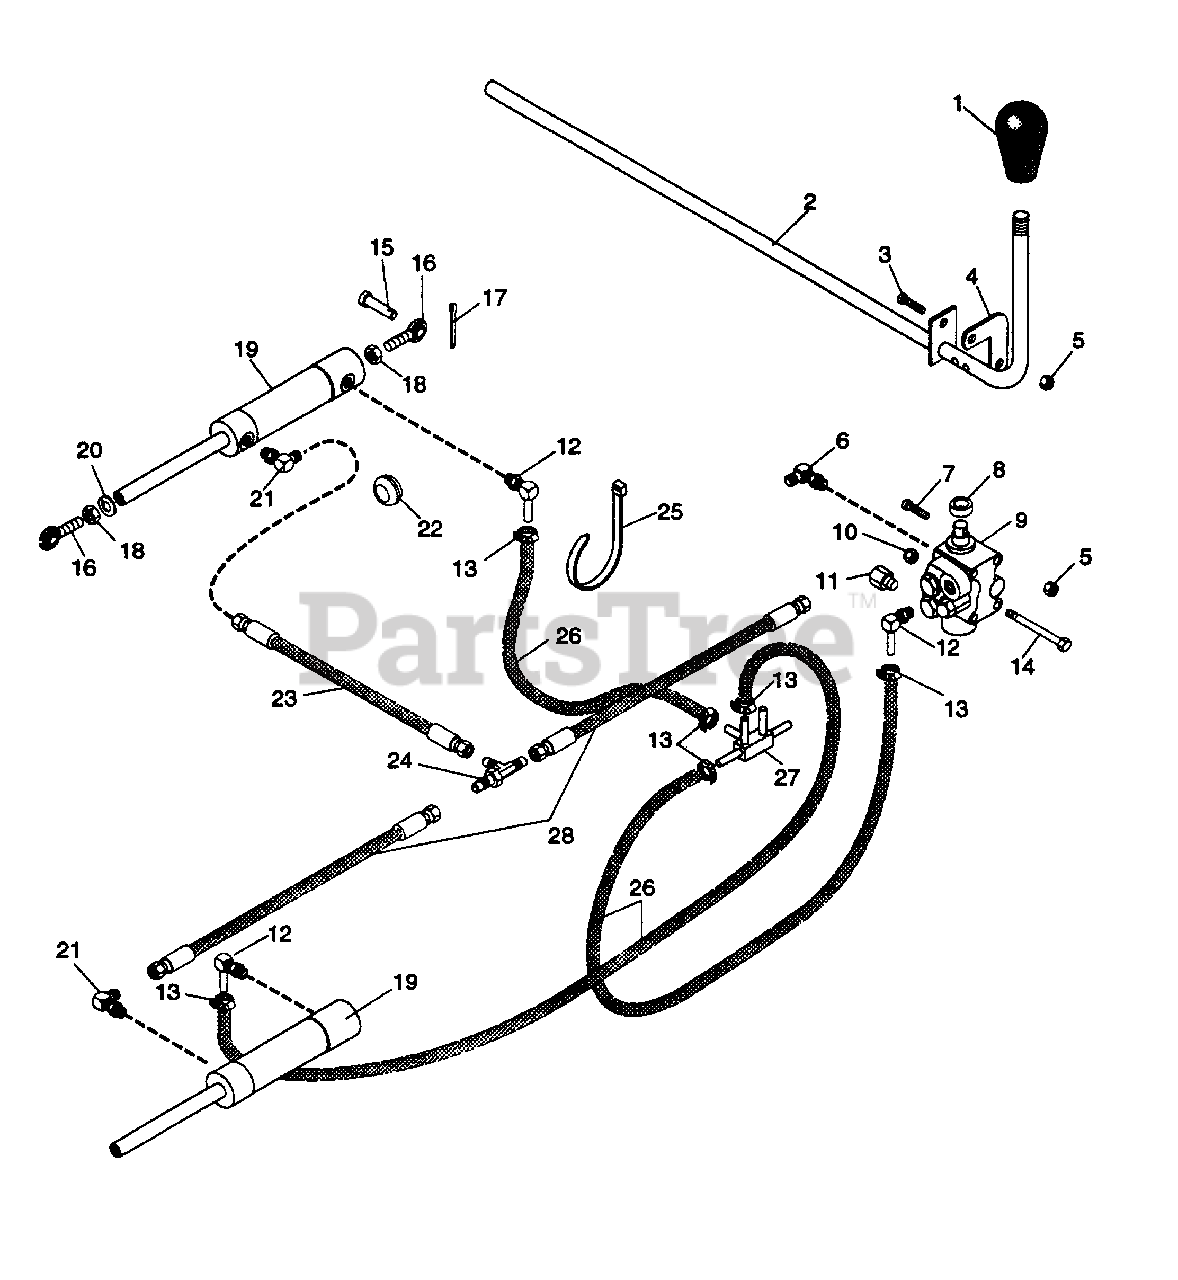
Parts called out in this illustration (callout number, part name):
1	KNOB, PTO
2	WLDMT, LIFT LEVER
3	SCR-MCH 10-24 X .625 P/HD
4	ROD, HYD CONTROL
5	NUT-LK 10-24 NY PL
6	ADPT 2503-6-4
7	SCR-MCH 10-24 X 1.00 PHCR
8	BUSH., S. 700 X 1.00 X .300 ST
9	VLV, HYDRAULIC
10	NUT-LK-NYL .250-20 PL
11	PLUG .44-20
12	FTG-ADPTR .562-18 ST THD
13	HOSE CLAMP
14	BLT-HEX .25-20 X 2.75
15	PIN-CLEV .50 X 1.330
16	ASM, ROD END RH
17	PIN-COTR .12 X 1.25 PL
18	NUT-JAM .50-2-PL
19	CYL, LIFT
20	WSHR-LOCK .50 REG.
21	ADPT 2503-6-6
22	GROMMET, 1.25
23	ASM, HYDRAULIC HOSE
24	ADPTR-BULKHEAD TEE .56-18
25	TIE WRAP, BLACK
26	HOSE, HYDRAULIC
27	FTG-MNFLD .38 X 1.50
28	ASM, HYDRAULIC HOSE
